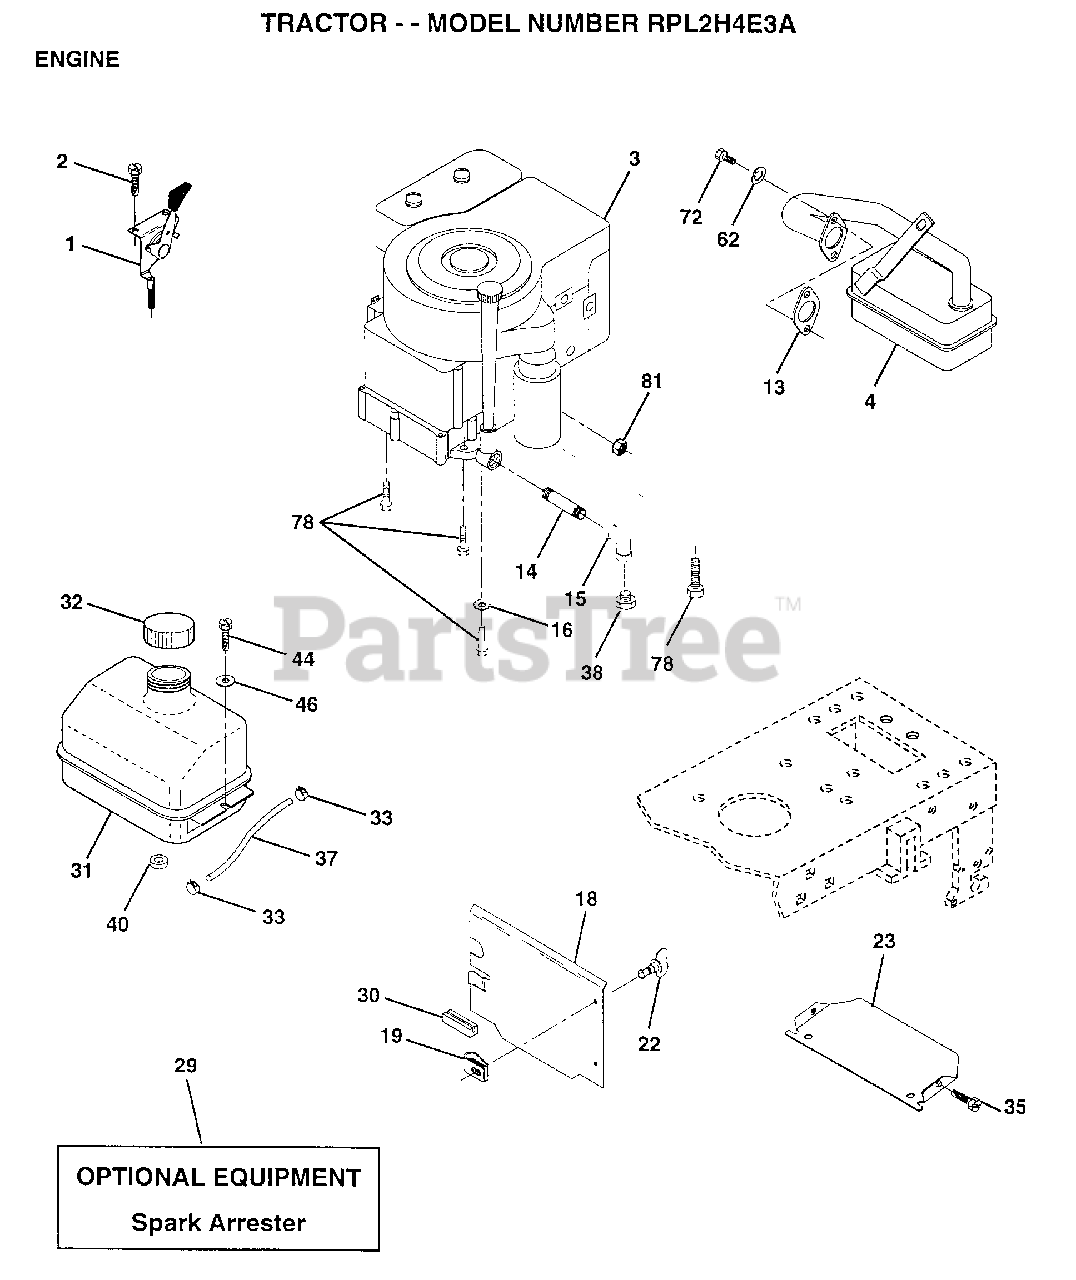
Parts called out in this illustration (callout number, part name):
1	CONTROL THROTTLE
2	SCREW LT
4	MUFFLER
13	GASKET ENG 1 313 LD TIN PLATED
14	PIPE NIPPLE
15	ELBOW
16	LOCKWASHER
18	SHIELD HEAT
19	RECEPTACLE LT
22	"STUD 1/4 TURN,BUS"
31	TANK.FUEL.LT.
32	CAP ASM FUEL
33	HOSE CLAMP
35	SCREW
37	LINE FUEL
44	SCREW HEX CRT
46	WASHER
62	LOCKWASHER
72	SCREW
78	SCREW
81	NUT
